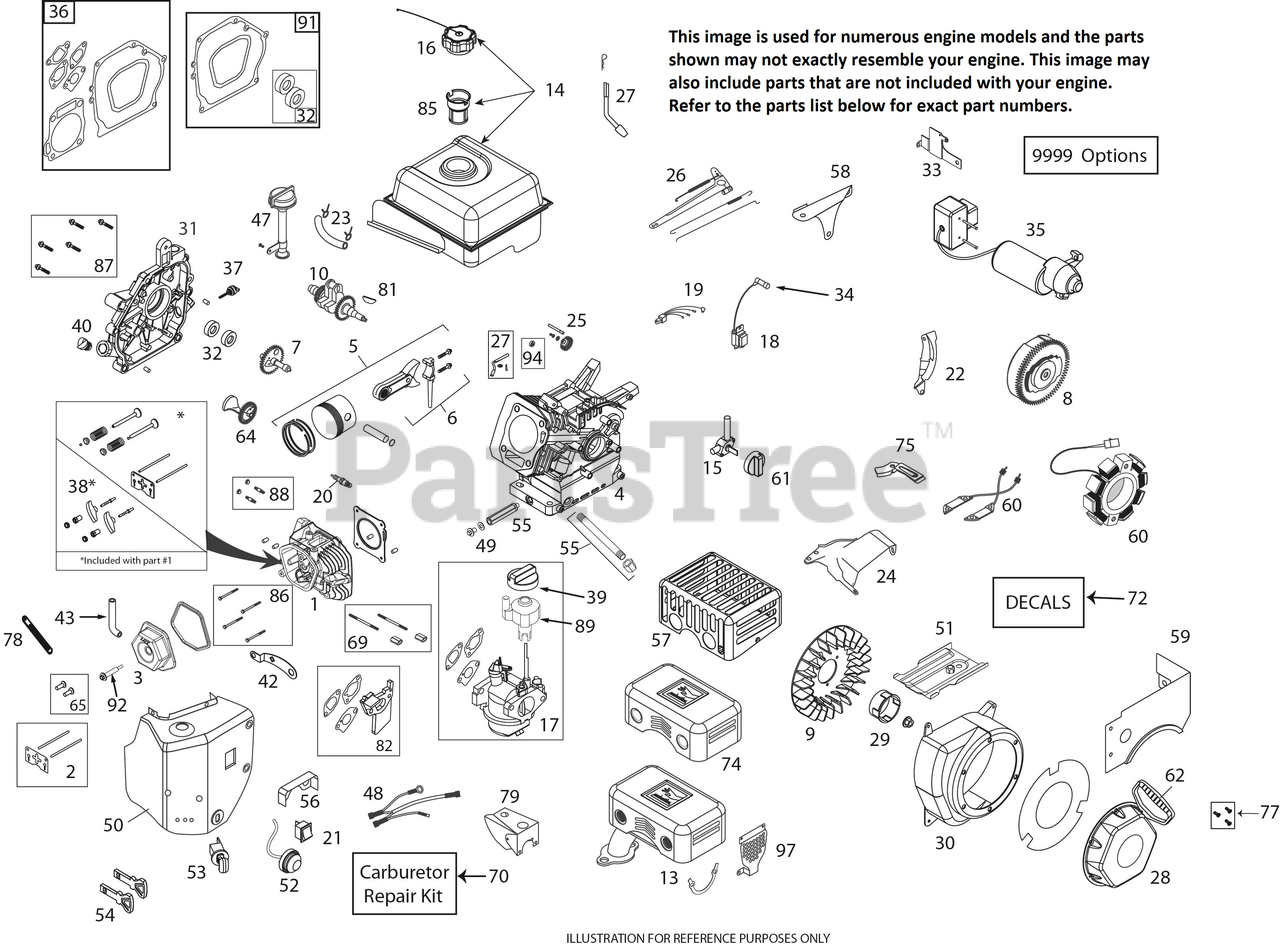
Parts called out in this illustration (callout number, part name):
1	CYLINDER HEAD ASSY (/GASKET)
2	PUSH ROD & PLATE KIT (W/GSKT)
3	VALVE COVER (W/GASKET)
4	CYLINDER
5	PISTON & ROD ASSEMBLY
6	CONNECTING ROD ASSEMBLY
7	CAMSHAFT - MCR
8	FLYWHEEL - ELECTRIC START
9	COOLING FAN - FLYWHEEL
10	CRANKSHAFT (#17 KEYED)
13	MUFFLER ASSEMBLY
14	FUEL TANK ASSEMBLY (GLS BLACK)
15	FUEL TANK ON/OFF VALVE
16	FUEL TANK CAP - (VENTED)
17	CARBURETOR (W/IDLE-DOWN)
18	IGNITION COIL (CDI) (STANDARD)
20	SPARK PLUG
21	ON/OFF SWITCH - ROCKER
23	FUEL HOSE KIT
24	SPEED CONTROL SHIELD-FIXED
25	GOVERNOR GEAR ASSEMBLY
26	GOVERNOR ARM & LINK KIT
27	GOVERNOR ARM PADDLE
28	RECOIL STARTER (GLS BLACK)
29	STARTER CUP
30	BLOWER HOUSING (GLS BLACK)
31	CRANKCASE COVER
32	OIL SEAL KIT
33	ELECT START SWITCHBOX BRACKET
34	SPARK PLUG BOOT (W/MTL SHIELD)
35	120V ELECTRIC STARTER W/BOLTS
36	ENGINE GASKET KIT
37	SMALL BLACK OIL DIPSTICK
38	ROCKER ARM KIT (W/GASKET)
39	CHOKE CONTROL KNOB (RED)
40	NON-REMOVABLE PLASTIC PLUG
42	CDI BOX BRACKET
43	BREATHER TUBE
47	HIGH OIL-FILL TUBE & CAP
48	WIRE HARNESS
49	OIL DRAIN PLUG (W/WASHER)
50	HEATER BOX ASSEMBLY (GLS BLK)
50	KIT,EXTREME WEATHER,AX414G2
51	SHIELD - CYLINDER
52	PRIMER BULB WITH HOSE
53	SAFETY KEY SWITCH (W/KEYS)
54	KEY, PUSH/PULL LCT (2/PACKAGE)
55	OIL DRAIN TUBE
56	CARBURETOR VAPOR SHIELD
57	CE COMPLLANT MUFFLER SHIELD
58	SHIELD - GOVERNOR LINKAGE
59	FUEL TANK SKIRT (GLS BLACK)
60	CHARGING COIL (60-WATT AC)
61	FUEL CONTROL KNOB (RED)
62	STARTER GRIP-SNOW (DELUXE)
64	COUNTER WEIGHT KIT
65	TAPPET KIT (SET OF 2)
69	CARB MTG STUD KIT 414CC
70	CARBURETOR REPAIR KIT
72	ARIENS 414 (ALL) SNW DCL KIT
75	SHIELD - FLYWHEEL
77	RECOIL BOLT KIT
78	BREATHER TUBE RETAINING STRAP
79	SHIELD - CARBURETOR COVER
81	WOODRUFF FLYWHEEL KEY 5-PACK
82	CARBURETOR SPACER
85	FUEL TANK STRAINER
86	HEAD BOLT KIT 291-414CC
87	CRANKCASE COVER BOLT KIT 414CC
88	MUFFLER MTG STUD KIT
89	SPEED CONTROL KNOB
91	CRANKCASE GASKET KIT(369-414)
92	VALVE COVER BOLT (SINGLE BOLT)
94	GOVERNOR SHAFT SEAL
97	MUFFLER MANIFOLD SHIELD
9999	HIGH ALT JET - 414CC L12 CARB
9999	HARDWARE KIT (4 M6X10 FLG BLT)
9999	STARTER SWITCH SCREWS
